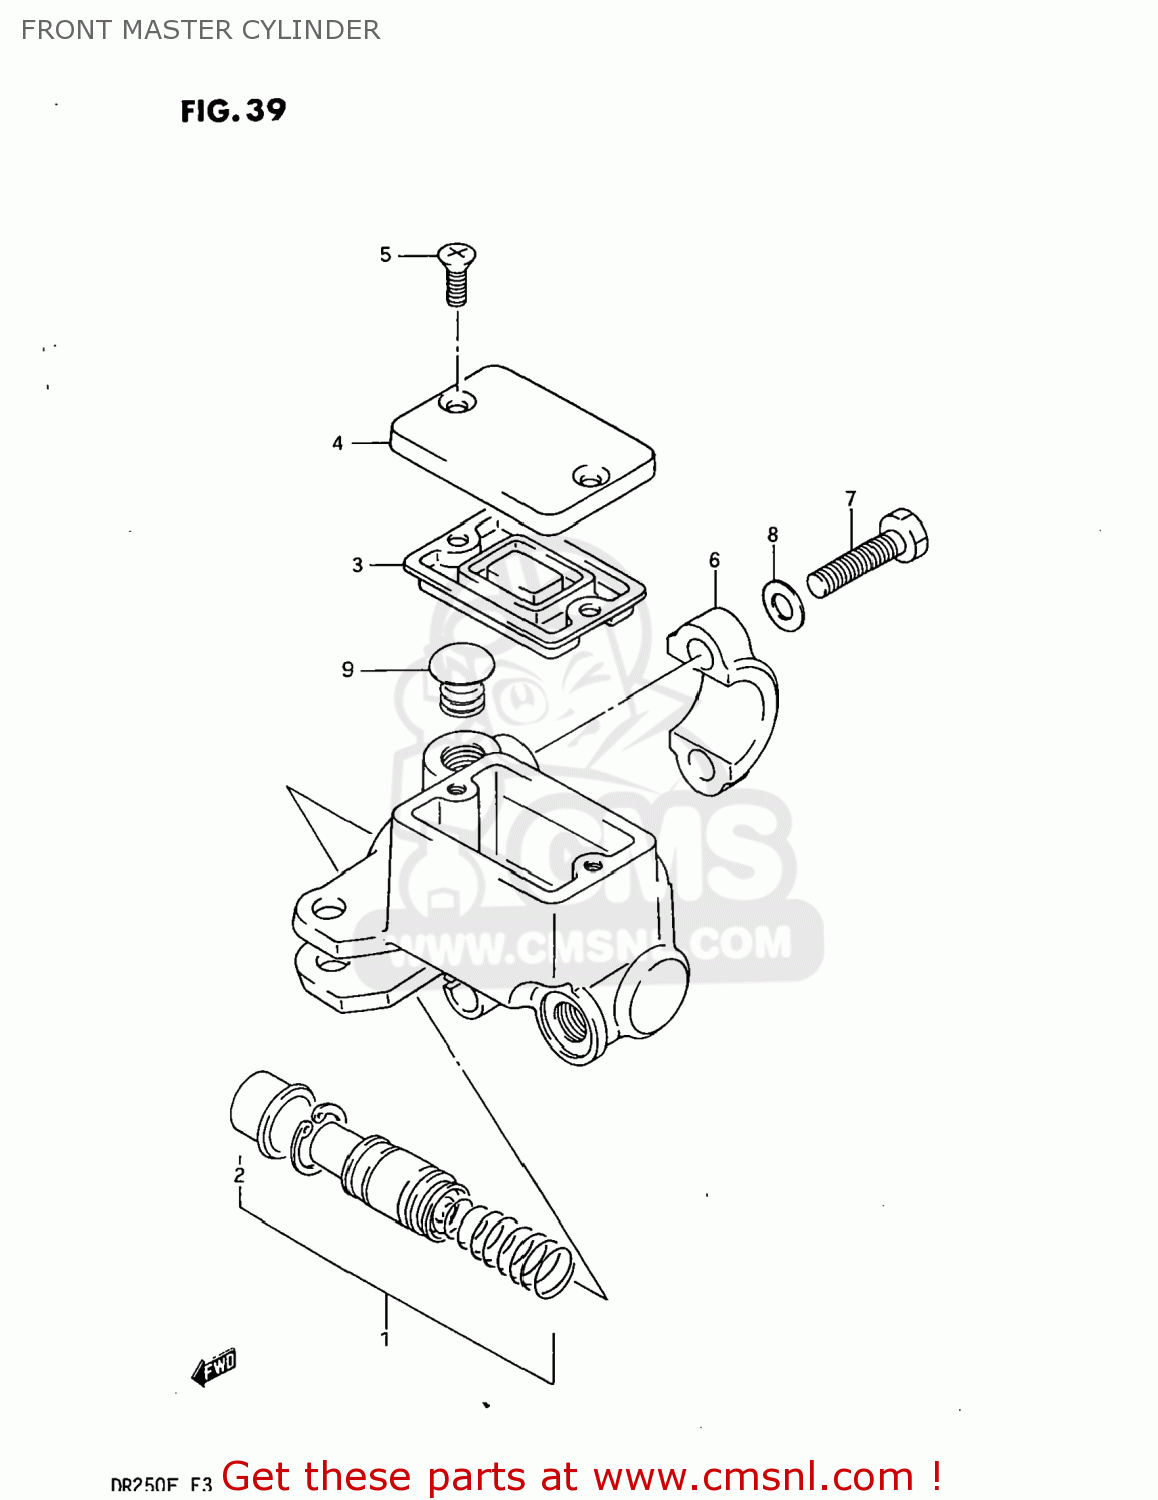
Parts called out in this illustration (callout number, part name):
1	PISTON/CUP SET
2	BOOT
3	DIAPHRAGM
4	CAP
5	SCREW
6	HOLDER
7	BOLT
8	WASHER
9	CAP(OD:14)
